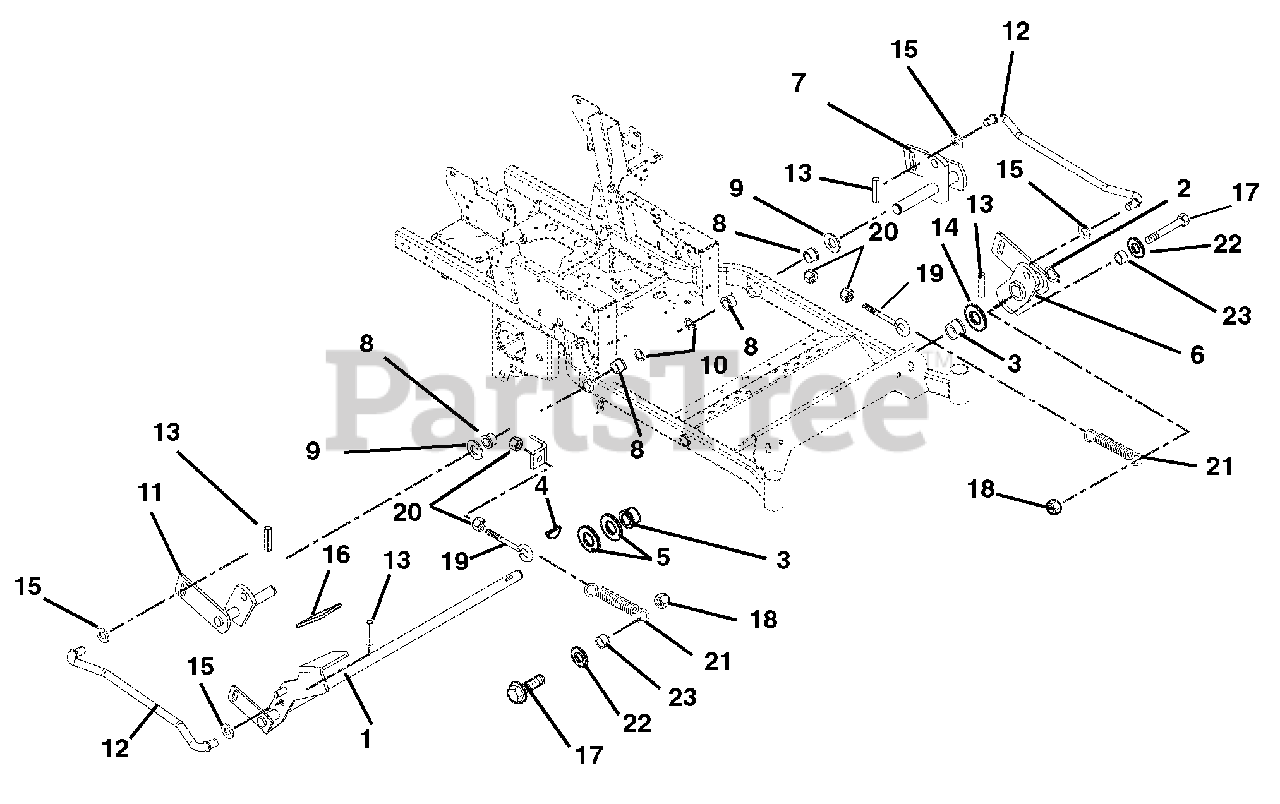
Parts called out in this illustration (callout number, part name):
1	Weldment, Mower Lift, Foot-Operated
2	Ring, Retaining External 1.00 x .078
3	Bushing, Flange
4	Key, Woodruff .25 x 1.00
5	Washer, Flat Steel 1.063 x 2.00 x .134
6	Lift Arm - Front
7	Weldment, Left Hand Rear Lift Arm
8	Bushing, Flange Nylon .762 x 1.0 x .580 x 1.48
9	Washer, Hardened Steel .758 x 1.23 x .031
10	Ring, Retaining External .689 x .077
11	Weldment, Right Hand Rear Lift Arm
12	Rod, Lift Assist
13	Pin, Roll .25 x 1.25 Stainless Steel
14	Washer, Hardened Thrust 1.00 x 1.55 x .03
15	Washer, Flat-Steel .630 x 1.250 x .062
16	Grip, Pedal
17	Bolt, Hex .38-16 x 1.00 Grade 5
18	Nut, Locking Jam Center .375-16
19	Eye-Bolt, .375-16 x 2.50
20	Nut, Hex Jam .375-16
21	Spring, Tension .162 x 1.25 x .25
22	Washer, Flat Steel .438 x 1.00 x .083
23	Spacer .377 x .624 x .235
